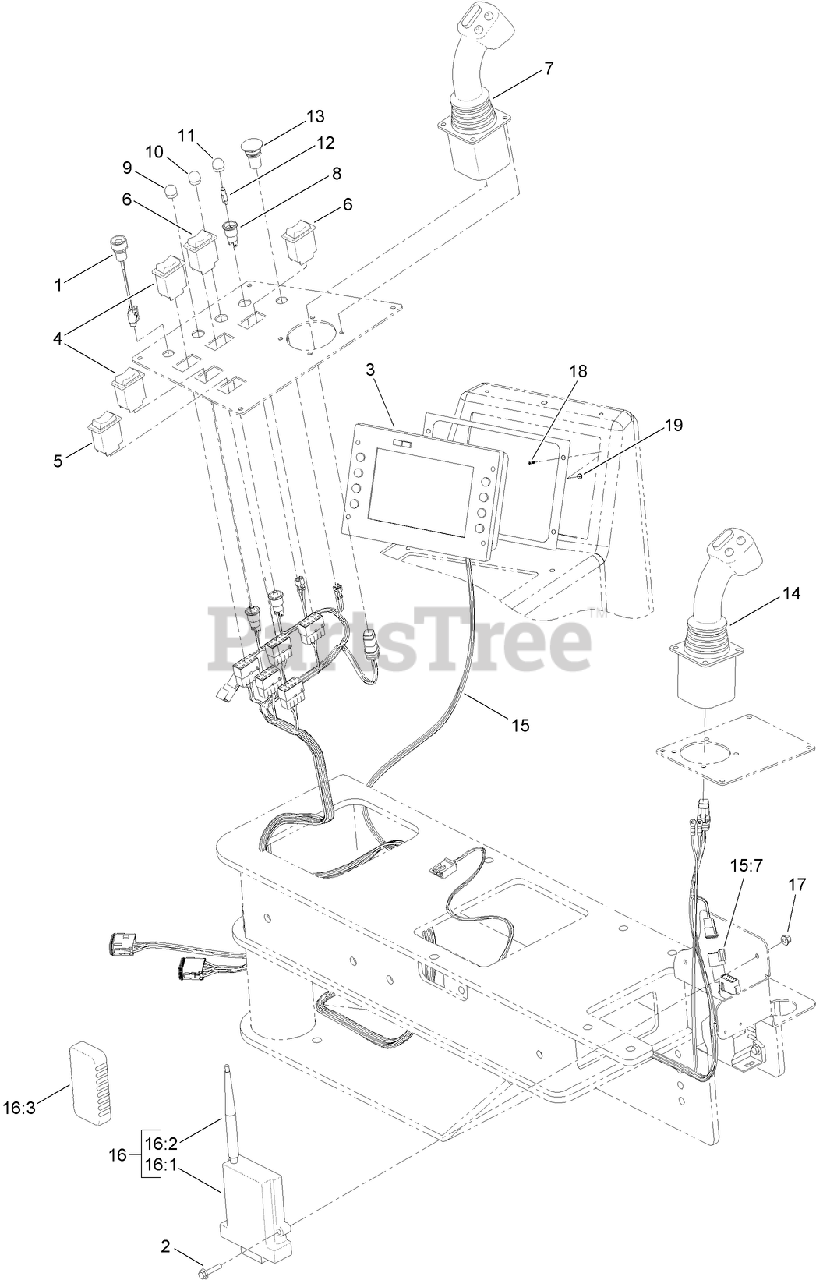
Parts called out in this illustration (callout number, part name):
1	SWITCH-START, GREEN BUTTON
2	SCREW-HHF
3	DISPLAY-DP600, UNPROGRAMMED
4	SWITCH-ROCKER, 2 POLE (ON/OFF)
5	SWITCH-ROCKER, 2 POLE
6	SWITCH-ROCKER, 1 POLE (ON)OFF/ON(OFF)
7	JOYSTICK-MODIFIED (LEFT HAND)
8	TYPE T-2 SOCKET ASM
9	LENS-DOME, FLUTED RED (TYPE T-2)
10	LENS-DOME, FLUTED GREEN (TYPE T2)
11	LENS-DOME, FLUTED AMBER (TYPE T2)
12	LAMP-LED
13	BUTTON-PUSH, RED MUSHROOM
14	JOYSTICK-CARRIAGE
15	HARNESS-WIRE, OPERATOR
15:7	RESISTOR-120 OHM
16	STANDARD EXIT SIDE LOCKOUT
16:1	BASE UNIT-LOCKOUT
16:2	ANTENNA-LOCKOUT
16:3	HANDHELD-LOCKOUT
17	NUT-FLANGE, NI
18	SCREW-PRH, SLOTTED
19	NUT-LOCK, NI
